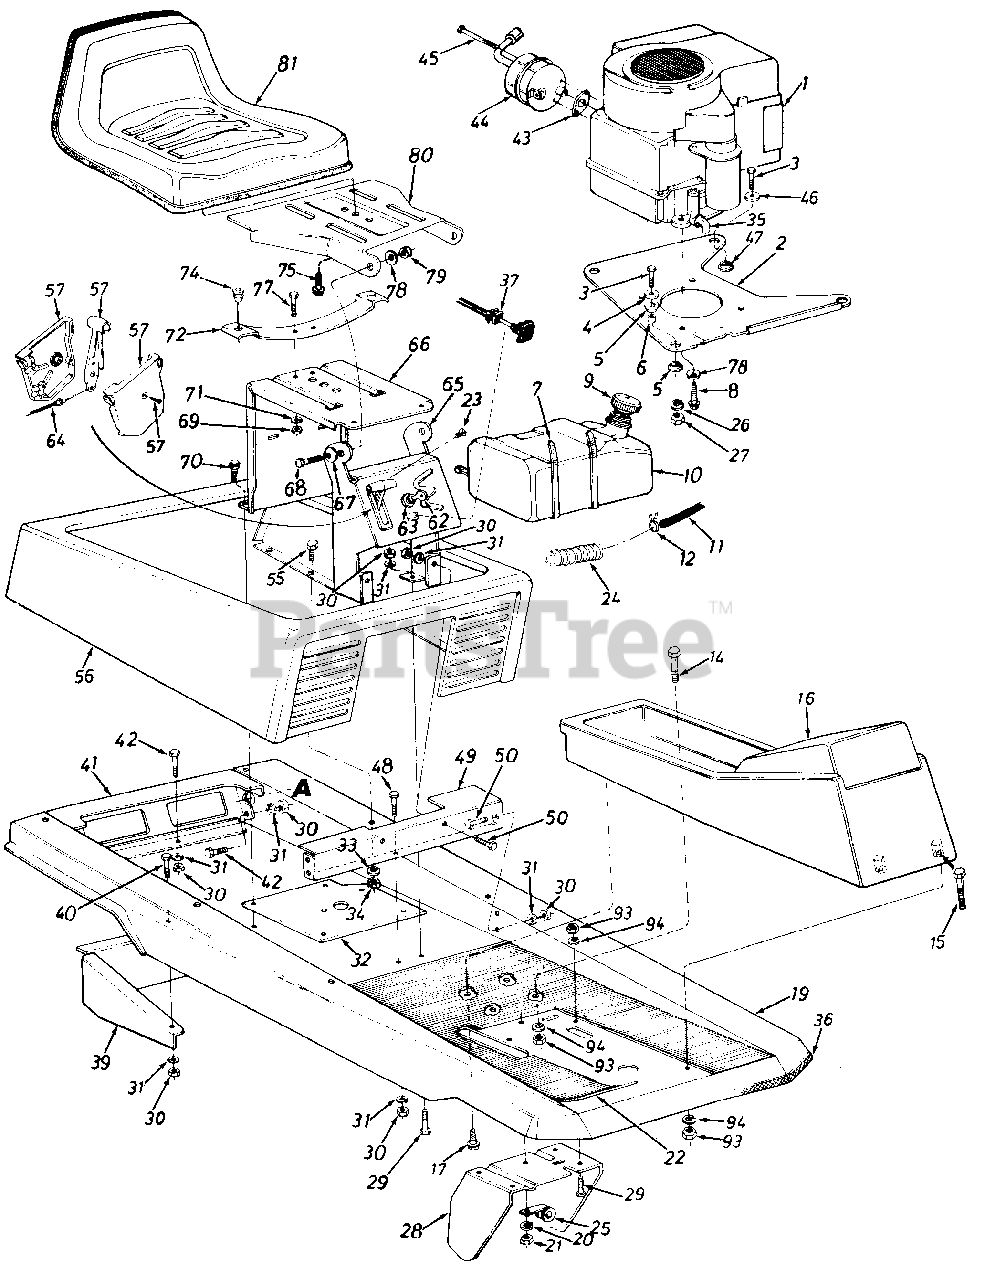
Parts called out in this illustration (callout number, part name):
1	Engine
4	Fl-Wash. .330" I.D. x 1.125" O.D.
5	Engine Mounting Grommet
6	Spacer.315" I.D. x .50" O.D. x .520" Lg .
7	Cable Tie 30.6 Lg.
8	Hex Wash. Hd. Self-Tap Scr. 3/8-16 x 1.25" Lg.
10	Fuel Tank
11	Gas Line-26 Inches
12	Hose Clamp-.406" Dia.
14	Hex Bolt 5/16-18 x 1.75" Lg.
15	Hex Bolt 5/16-18 x 2.0" Lg.
16	Front Console
17	Plastite Scr. 5/16 x 1.25" Lg.
19	Main Frame
20	L-Wash. 5/16" I.D.*
21	Hex Nut 5/16-18 Thd.
23	Truss Mach. AB-Tap Scr. #10 x .50" Lg.
24	Convoluted Conduit
26	L-Wash. 5/16" I.D.
27	Hex Nut 5/16-24 Thd.*
28	Clutch-Brake Pedal Ass'y.
29	Hex Bolt 5/16-18 x .75" Lg.*
30	Hex Nut 5/16-18 Thd.
31	L-Wash. 5/16" I.D.*
32	Mounting Brkt. Variable Speed Pulley
33	L-Wash. 1/4" I.D.
34	Hex Nut 1/4-20 Thd.*
35	90ø Elbow Male To Female
36	Trim Strip 18" Lg.
37	Choke Control
43	Exhaust Gasket
44	Muffler Ass'y.
45	Shld. Bolt
46	Fl-Wash. .33" I.D. x 1.25" O.D.
47	Flange Wash. .32" I.D. x .75" O.D.
48	Hex Bolt 5/16-18 x .75" Lg.
49	Seat Support & Frame Brkt.
50	Hex Bolt 5/16-18 x .75" Lg.
55	Hex Bolt 1/4-20 x .50" Lg.*
56	Engine Cover Ass'y.
57	Throttle Control Box Ass'y.
62	Ignition Key
63	Ignition Switch
64	Throttle Control Wire
68	Hex Bolt 5/16-18 x .75" Lg.
69	Hex Nut 5/16-18 Thd.*
70	Hex Self-Tap Scr. 5/16-18 x .75" Lg.
71	L-Wash. 5/16" I.D.
72	Seat Spring
75	Hex Wash. Hd. Tap Scr. 3/8- 16 x 3/4 " Lg .
77	Hex Bolt 5/16-18 x .75" Lg.*
78	Bell-Wash. .345" I.D. x .88" O.D.
79	Hex Cent. L-Nut 5/16-18 Thd.
80	Seat Pivot Bracket
81	Seat Ass'y. Comp.
93	Hex Nut 5/16-18 Thd.
94	L-Wash-5/16" I.D.*
